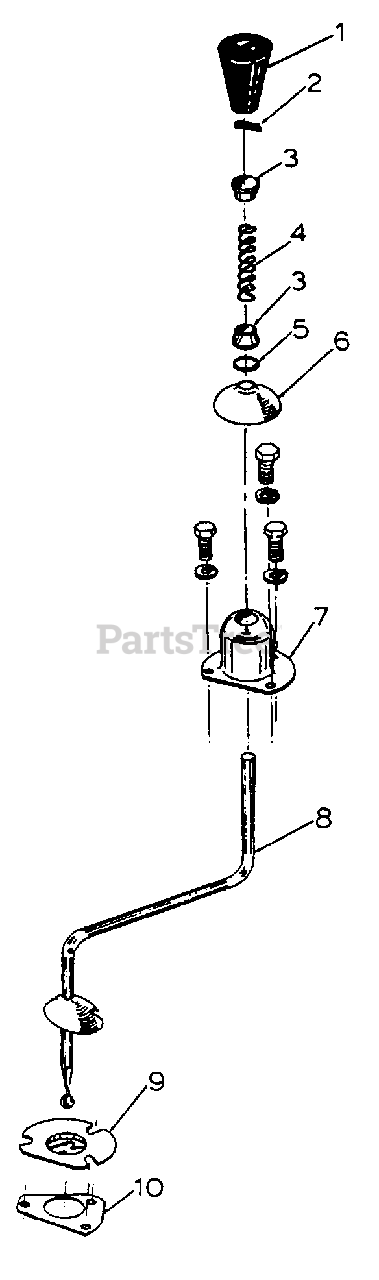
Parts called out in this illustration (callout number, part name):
1	Knob w/Product Graphic, Shift Handle
2	Pin, Gear Shift Swivel Retainer Pin
3	Retainer, Gear Shift Swivel Spring
4	Spring, Gear Shift Lever
5	O-Ring, 1/2 X 5/8 X 1/16
6	Shield, Gear Shift Lever
7	Housing Assy, Bell
8	Lever Assy, Gear Shift
9	Guide, Gear Shift Lever
10	Gasket, Housing
